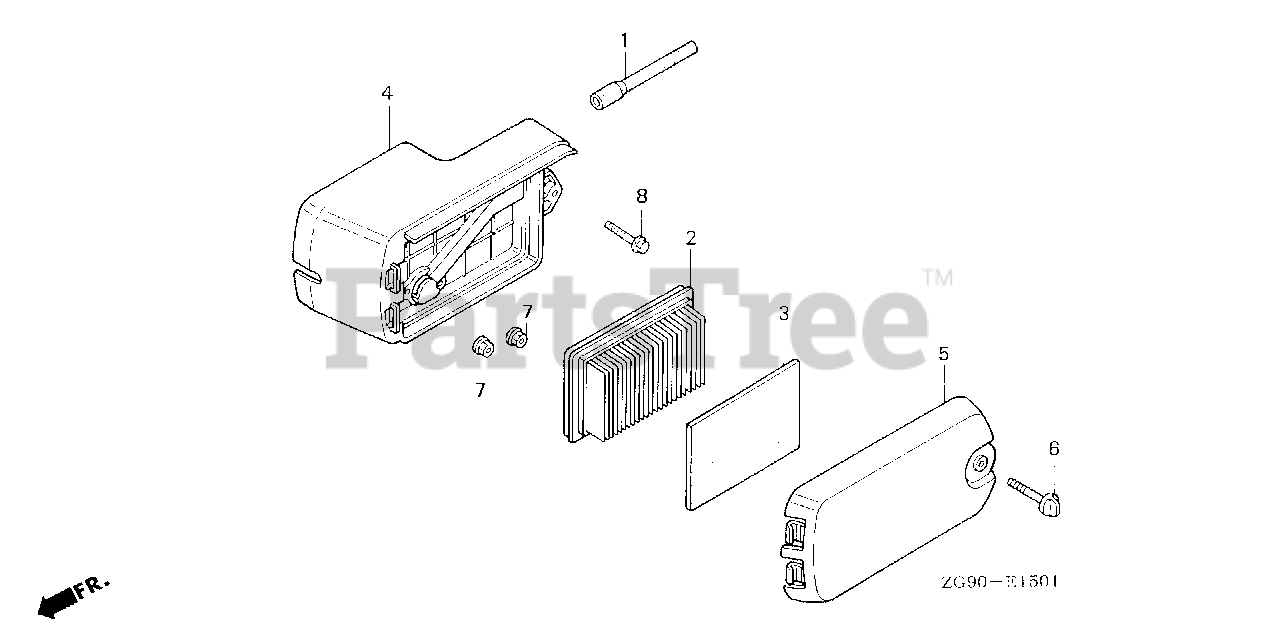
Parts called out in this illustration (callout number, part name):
1	TUBE, BREATHER (110MM)
2	ELEMENT, AIR CLEANER
3	FILTER (OUTER)
4	HOUSING, AIR CLEANER
5	COVER, AIR CLEANER
6	BOLT, AIR CLEANER (6MM)
7	NUT, FLANGE (6MM)
8	BOLT, FLANGE (6X32)
